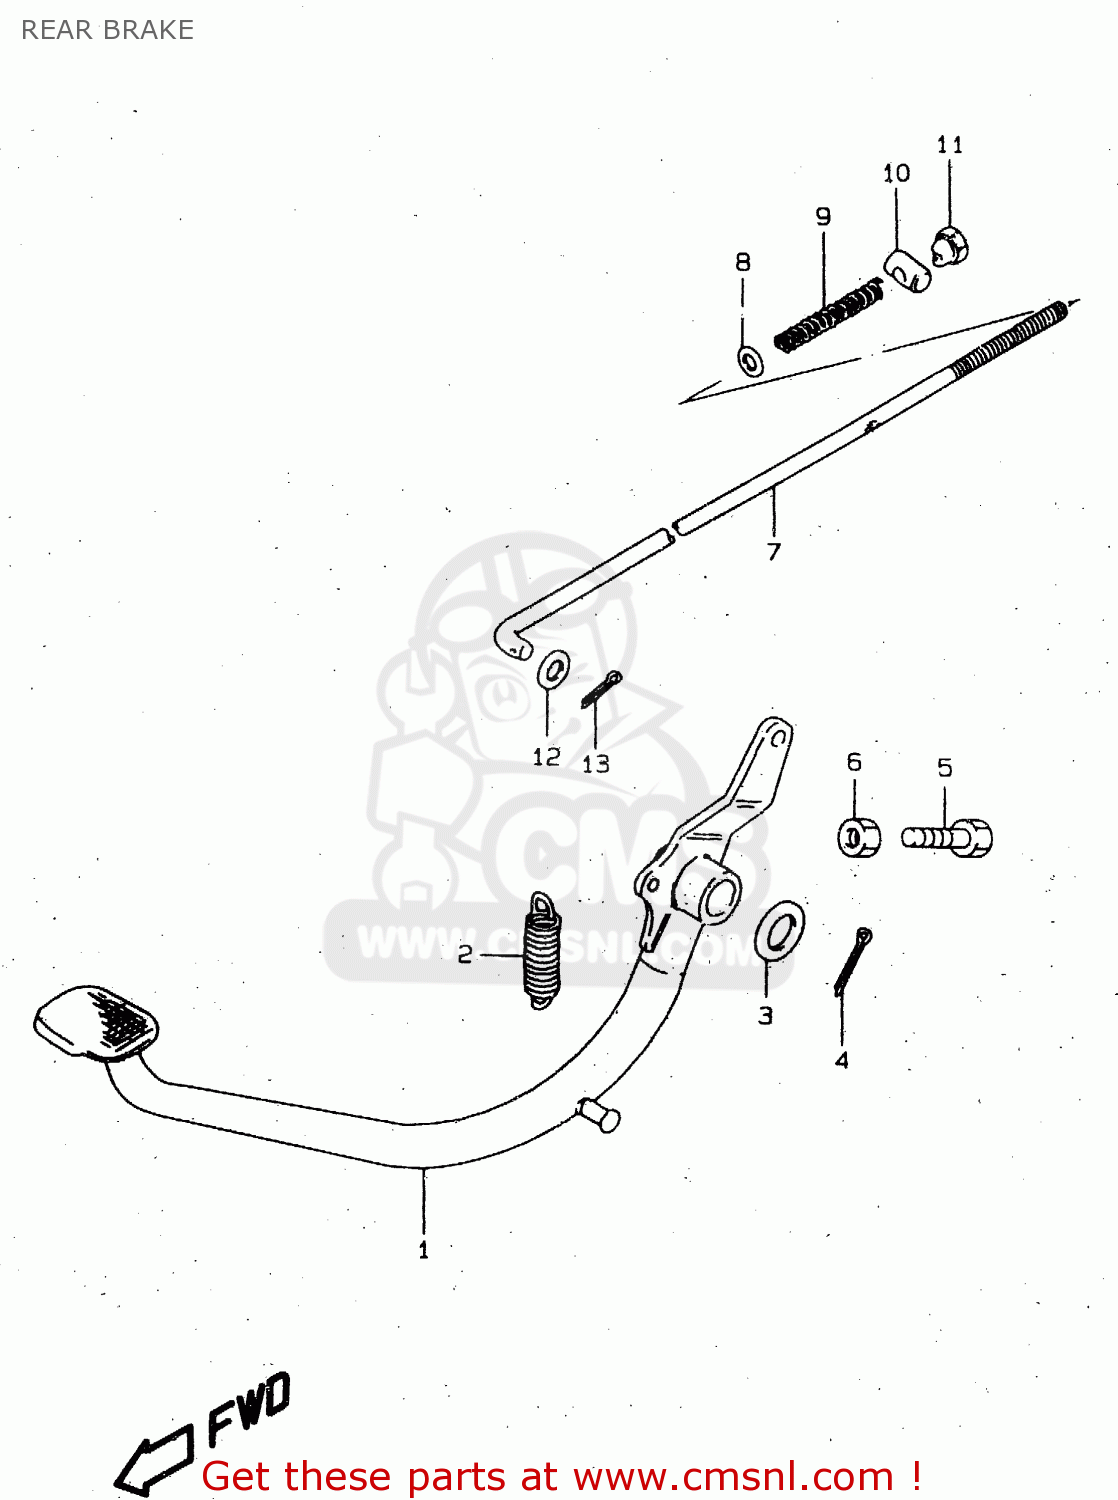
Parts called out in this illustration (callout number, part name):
1	PEDAL,BRAKE
2	SPRING
3	WASHER(15.5X26X2.3)
4	COTTER PIN
5	BOLT(6X23)
6	NUT 6MM
7	ROD ASSY,RR BRAKE
8	WASHER
9	SPRING
10	PIN(13X18)
11	NUT
12	WASHER
13	PIN 20X20
